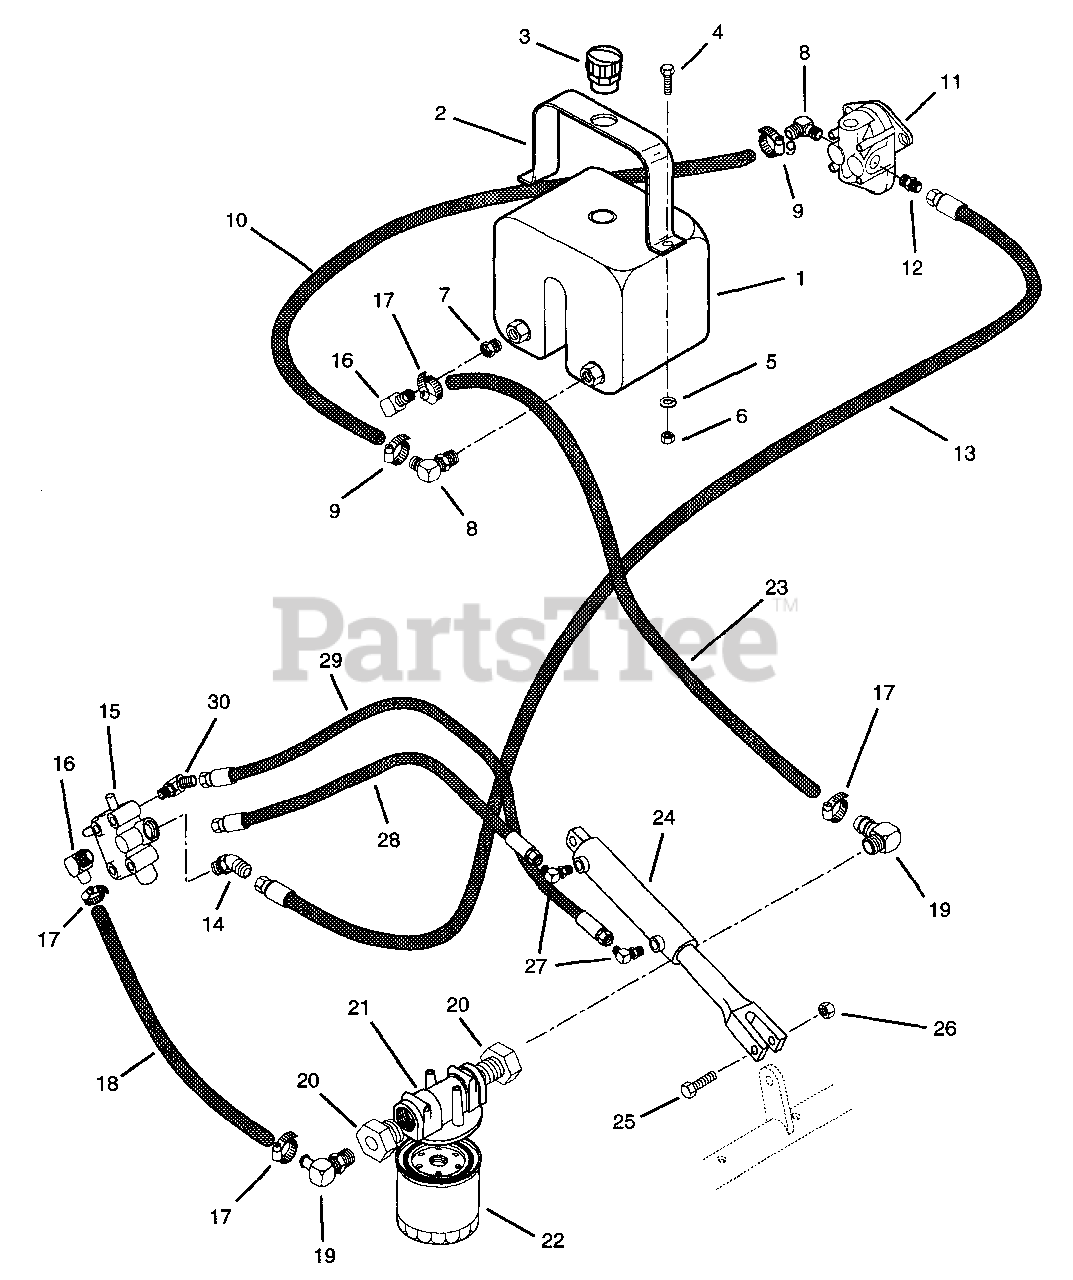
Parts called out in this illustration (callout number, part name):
1	Tank, Hydraulic
2	Strap, Tank
3	Cap, Filter
4	Bolt-Hex .31-18 .75 Plated Grade 5
5	Washer-Lock .313 x .078 Plated Medium
6	Nut-Hex .312-18 Zinc Grade 2
7	Fitting 10
8	Fitting 10HS
9	Clamp-Hose .219 x .625
10	Hose 300 PSI .625 x 15
11	Praker Pump
12	Straight Thread Connector
13	Hydraulic Hose Assembly .38 x 25.5
15	Parker Valve
16	Fitting 6HS-6MB90
17	Clamp-Hose .562" x 1.06
18	Hose 300PSI .375 x 18
19	90 Deg Hose Insert
20	Fitting 12MP-6FP
21	Filter Mount and Filter(includes 09405700)
22	Hydraulic Filter
23	Hose 300PSI .375 x 8
24	Hydraulic Cylinder
25	Bolt-Hex .50-13 x 1.75
26	Nut-Locking Unitorque .50
27	Adapter 4MJ-4MP90
28	Hydraulic Hose Assembly .25 x 25
29	Hydraulic Hose Assembly .25 x 33
30	Fitting 6MJ-6MB45
